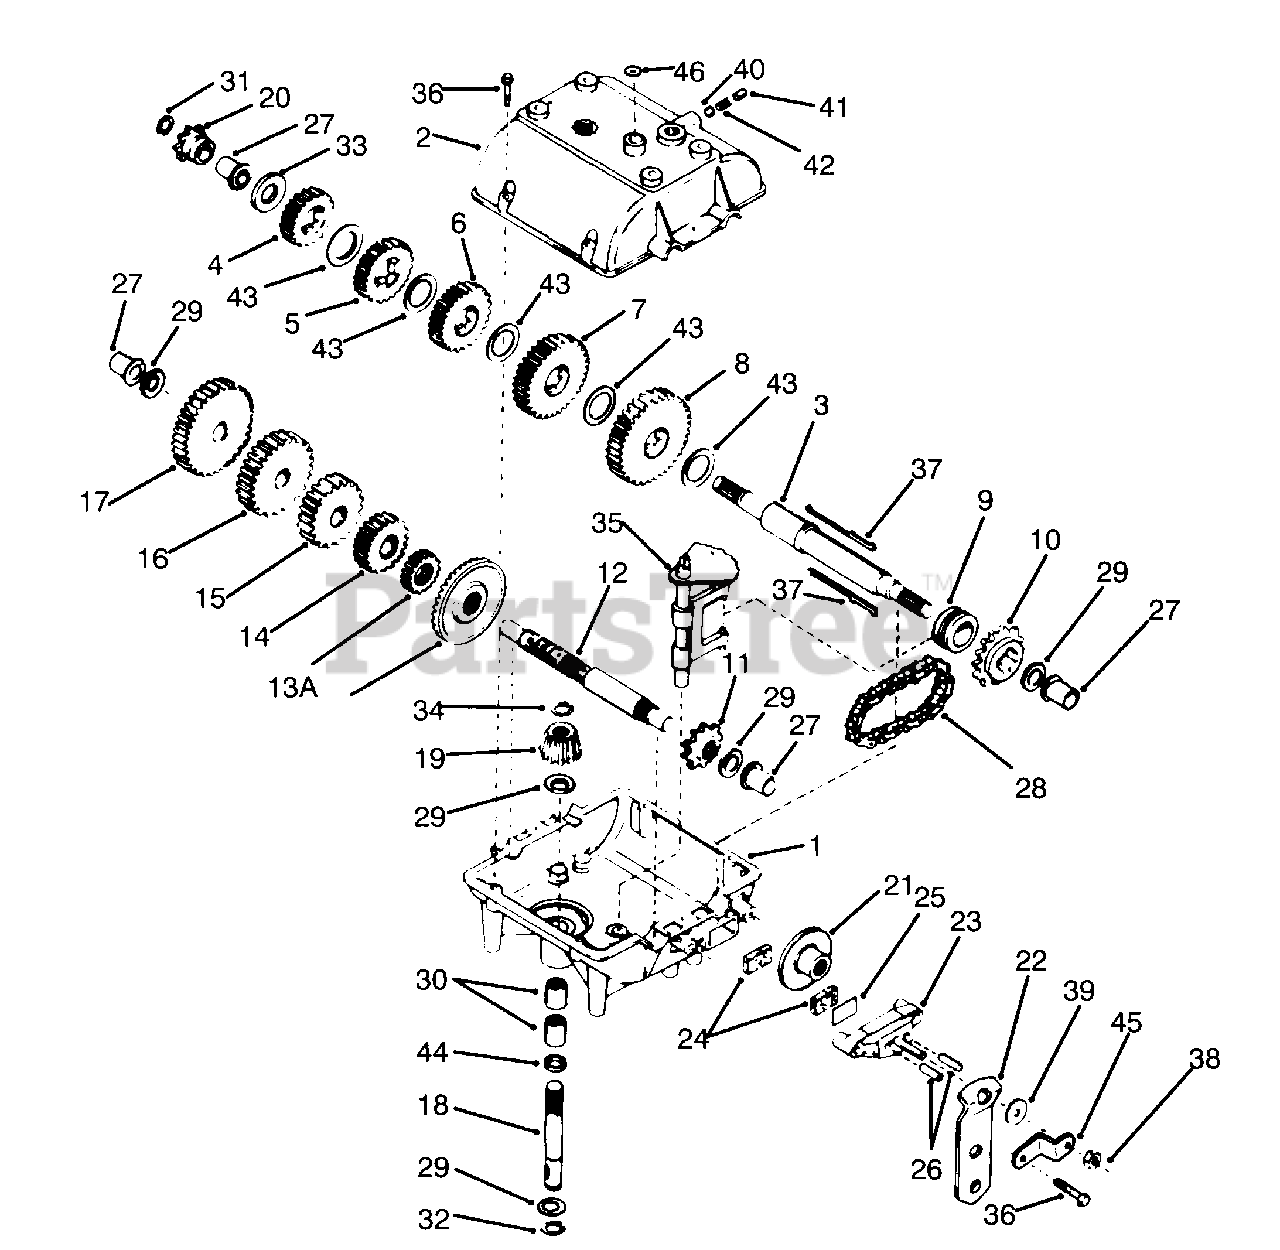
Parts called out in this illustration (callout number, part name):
1	Case-Transmission
2	Cover-Transmission
3	Shaft-Output
4	A Gear-Spur (20 Teeth)
5	Gear-Spur (22 Teeth)
6	Gear-Spur (25 Teeth)
7	Gear-Spur (30 Teeth)
8	Gear-Spur (35 Teeth)
9	Collar-Shift
10	Sprocket (18 Teeth)
11	Sprocket (9 Teeth)
12	Shaft-Counter
13	Gear-Bevel (42 Teeth)
13A	Gear-Spur (15 Teeth)
14	Gear-Spur (20 Teeth)
15	Gear-Spur (25 Teeth)
16	Gear-Spur (28 Teeth)
17	Gear-Spur (30 Teeth)
18	Shaft-Input
19	Bevel-Pinion, Input
20	Sprocket (8 Teeth)
21	Disk-Brake
22	Lever-Brake
23	Holder-Pad, Brake
24	Pad Brake
25	Plate-Pad, Brake
26	Pin-Dowel
27	Bushing-Flange
28	Chain-Roller (No. 41 Chain, 24 Links)
29	Washer-Thrust
30	Bearing-Needle
31	Ring-Retaining
32	Ring-Retaining
34	Ring-Retaining
35	Assy. Rod & Fork-Shift
36	Screw-Thread Forming
38	Nut-Lock
40	Ball-Steel
41	Screw-Set
43	Washer-Thrust
45	Bracket-Lever, Brake
46	Seal-Square Cut
